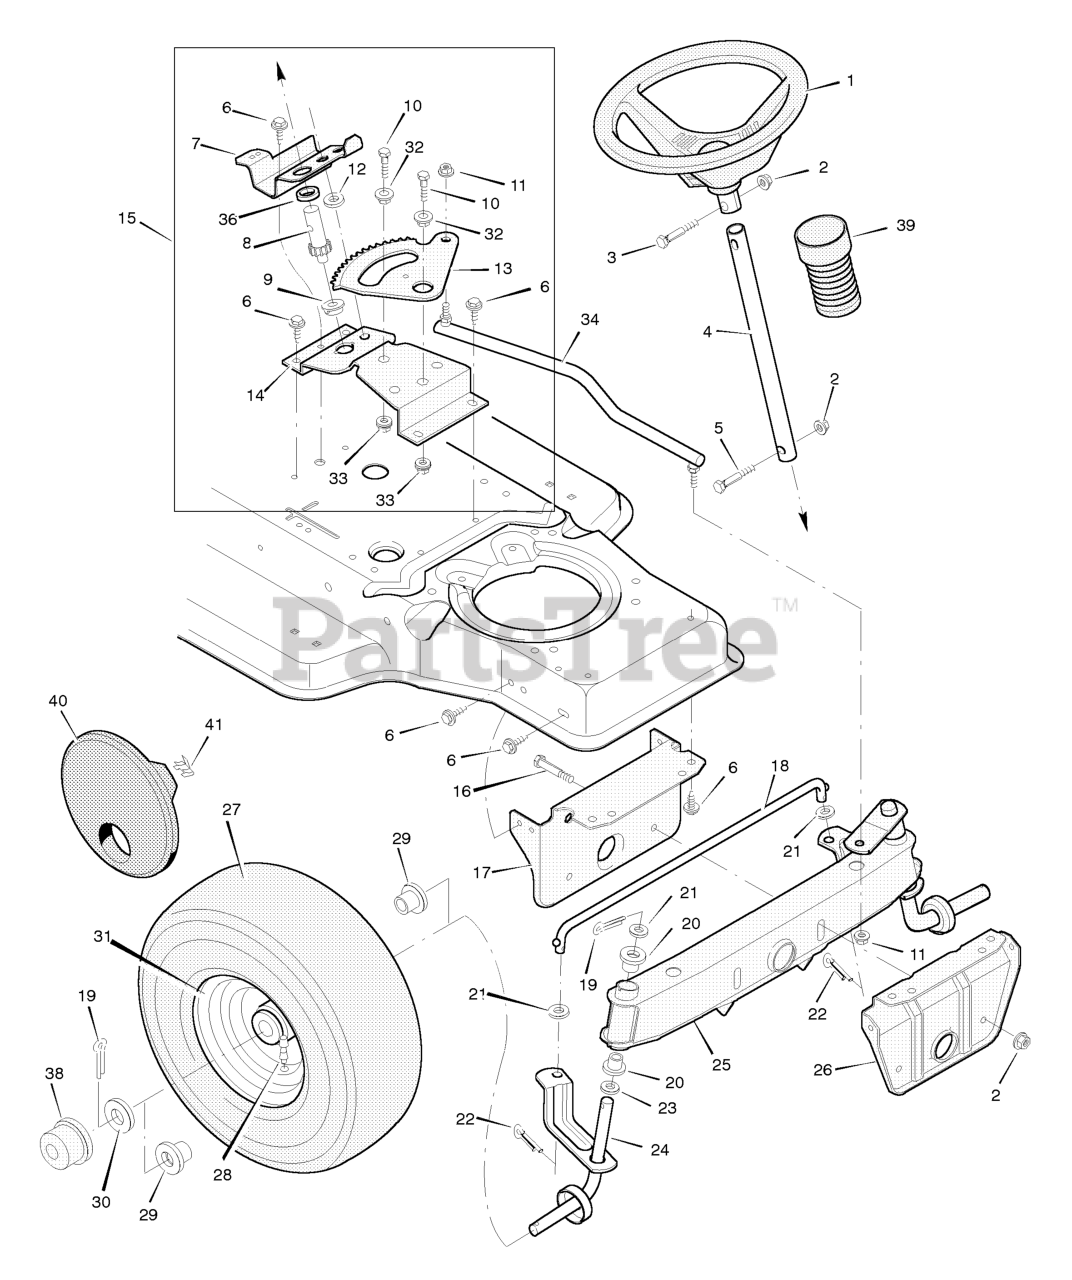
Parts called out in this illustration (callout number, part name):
1	Wheel, Steering
2	Nut, Hex
3	Bolt, Hex
4	Post, Steering
5	Bolt, Hex
7	Bracket, Sector
8	Gear, Pinion
9	Bearing
10	CAPSCREW, Hex Head, 5/16-18 x 1
11	Locknut, Flange
13	Gear, Sector
14	Bracket, Sector
15	Kit, Steering Gear
16	Bolt, Hex
17	Support, Rear Axle
18	Rod, Tie
19	Pin, Cotter
20	Bearing
22	Pin, Cotter
24	Spindle Assembly, Right
25	Spindle Assembly, Axle & Left
26	Support, Front Axle
27	Tire *
28	Stem, Valve
29	Bearing, Wheel
31	Wheel & Tire Assembly
32	Bearing
33	Locknut, Flange
34	Link, Drag
36	Spacer, Pinion Gear
38	Hub Cap
39	Bellows
40	Disc, Wheel
41	Clip, Retainer
